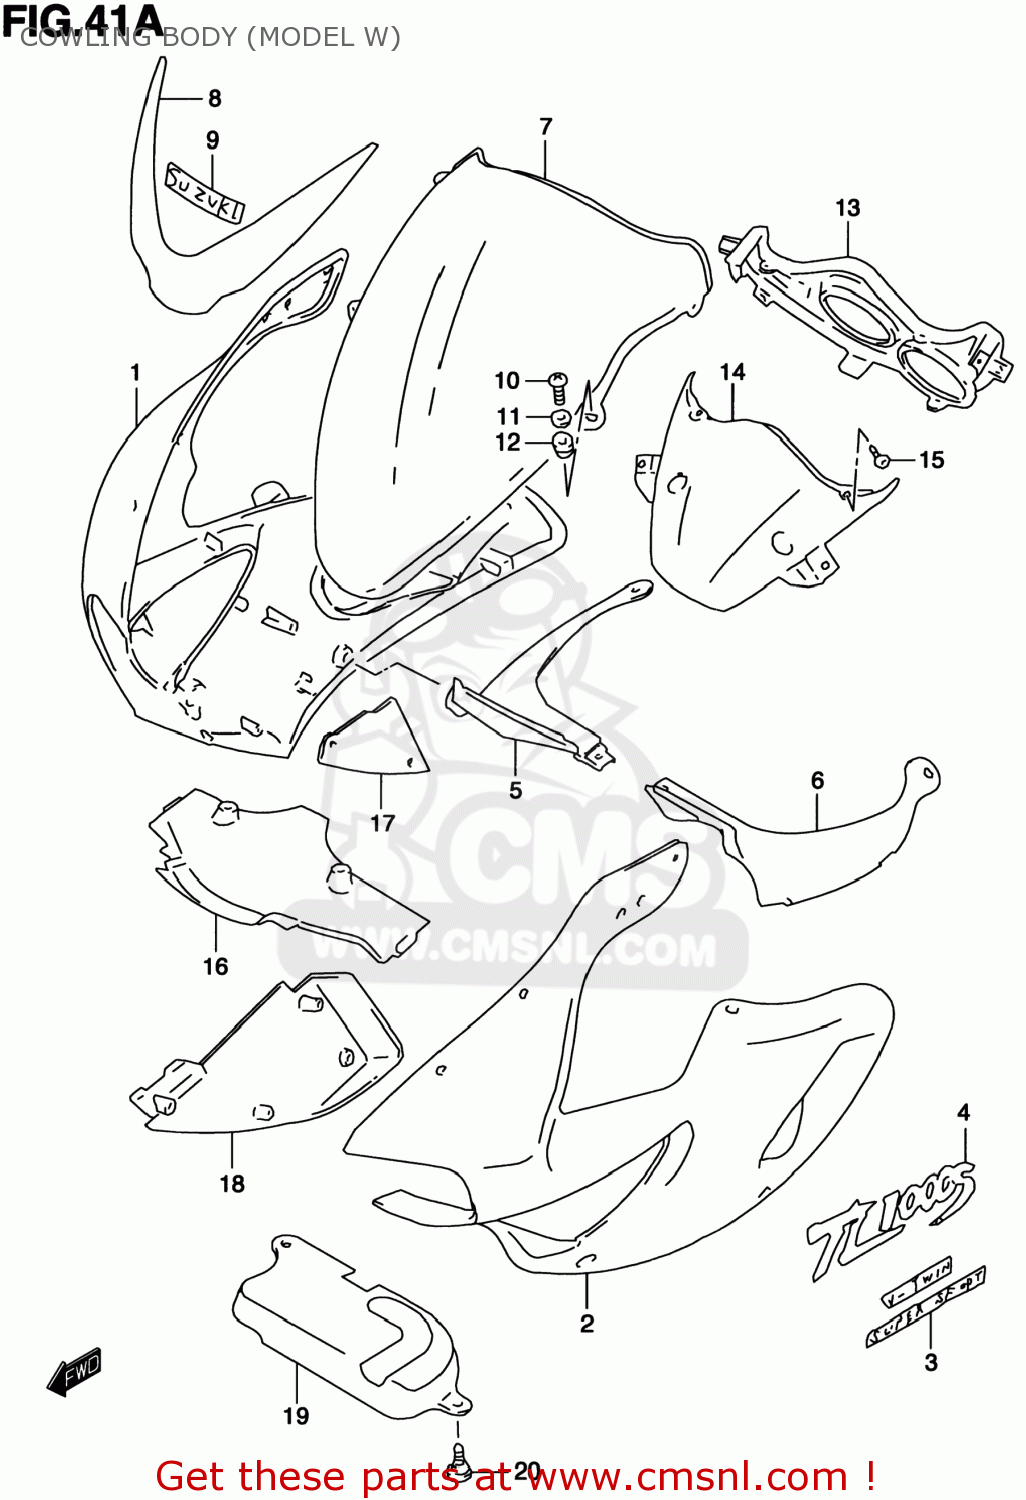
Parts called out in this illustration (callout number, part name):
1	COWLING,SIDE,R(RED)
2	COWLING,SIDE,L(RED)
3	EMBLEM,COWLING SIDE
4	EMBLEM,COWLING SIDE ,TL1000S
5	PANEL,SIDE,RIGHT
6	PANEL,SIDE,L
7	WINDSCREEN(SILVER)
8	TAPE,WINDSCREEN
9	EMBLEM(SILVER)
10	SCREW(5X14)
11	WASHER
12	NUT
13	PANEL,METER
14	PANEL,FR
15	CLIP(BLACK)
16	COWLING,CTR LWR
17	COWLING,INNER,R
18	COWLING,INNER,L
19	COVER,COWLING FR LWR
20	BOLT
